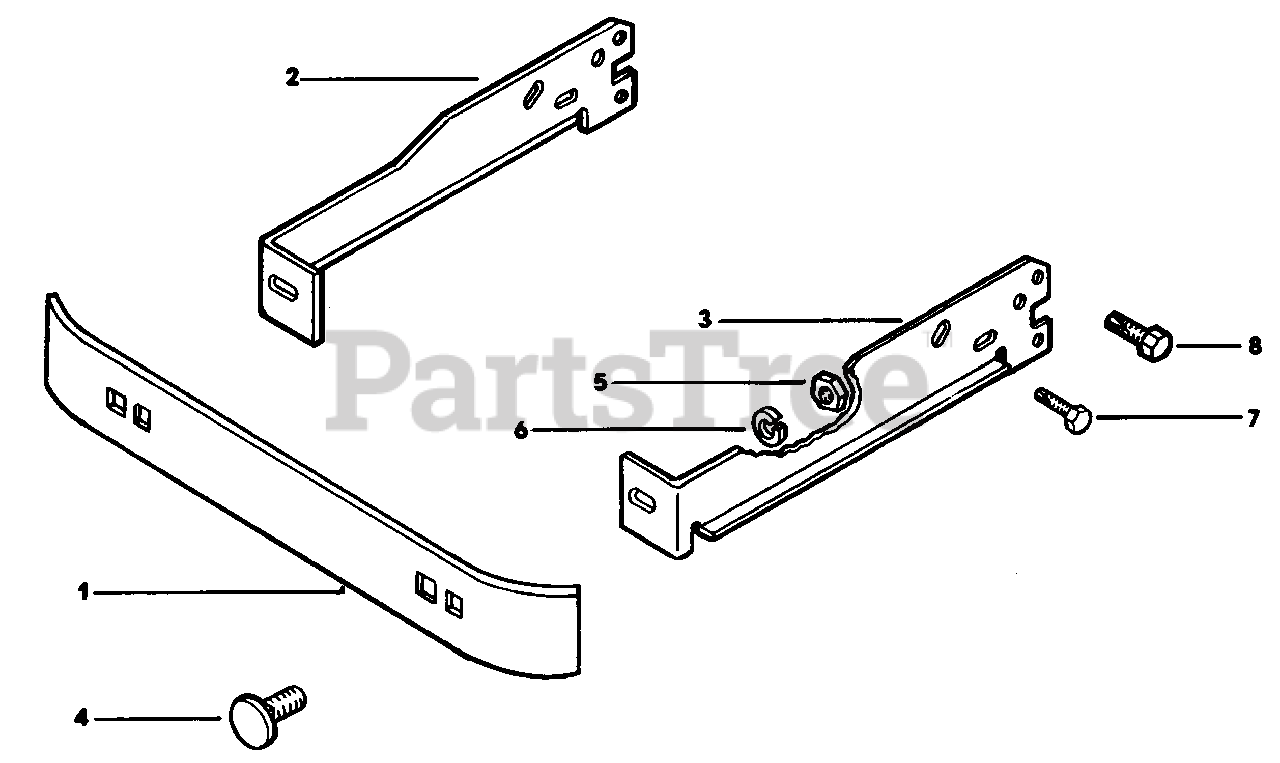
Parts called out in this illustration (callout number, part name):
1	Front Bumper
2	Bumper Side Support R.H.
3	Bumper Side Support L.H.
4	Bolt, Carriage 5/16-18 x 1" Plated
5	Nut, Hex 5/16-18 Plated
6	Washer, Spring lock 5/16 Plated
7	Hex Hd. Thread Forming Screw 1/4-20 x 3/4
8	Hex Hd. Thread Forming Screw 5/16-18 x 3/4
